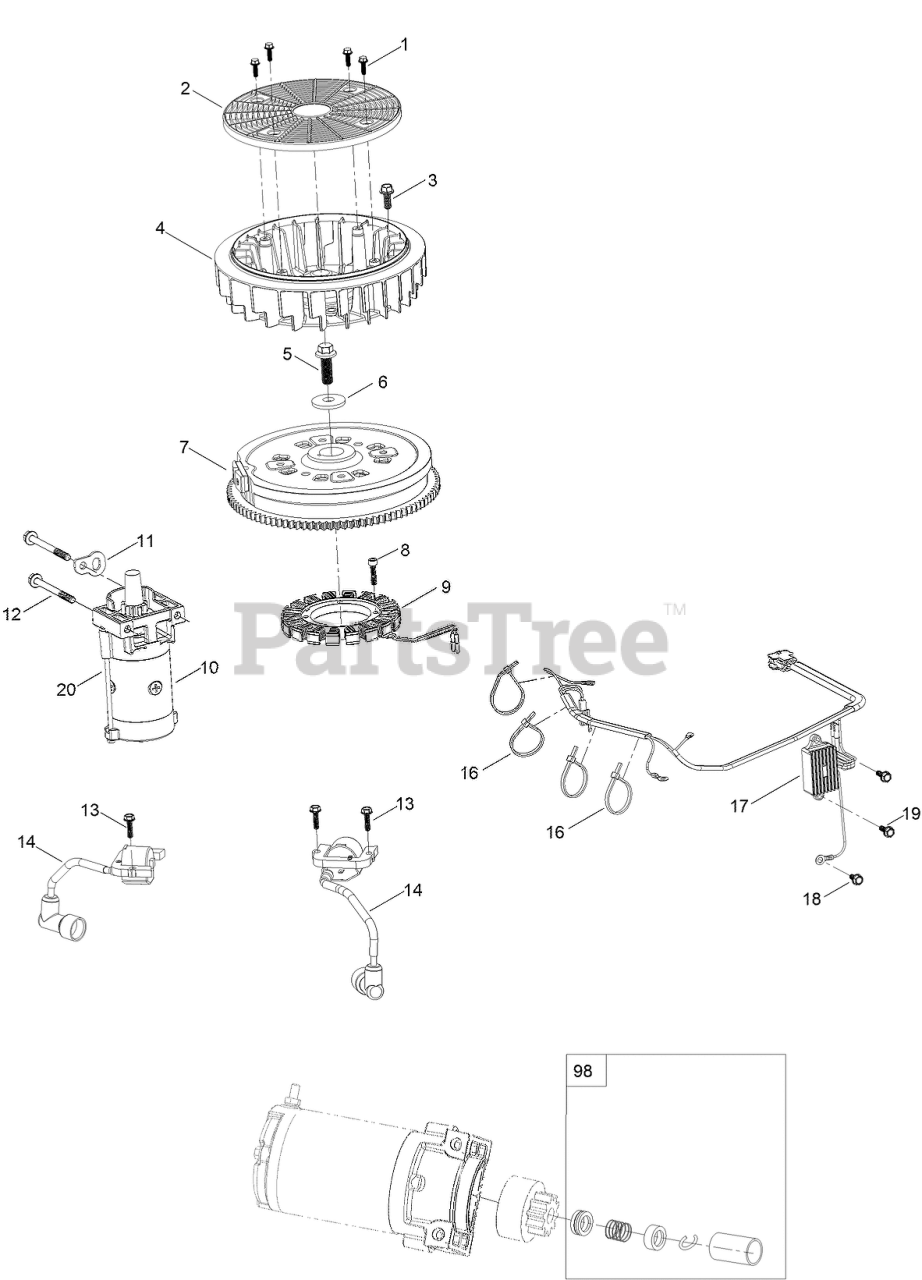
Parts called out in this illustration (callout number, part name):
1	SCREW-HWH
2	SCREEN-ROTATING
3	SCREW-HWH
4	FAN-COOLING
5	SCREW-HWH
6	WASHER-FLAT
7	FLYWHEEL
8	SCREW-HSH
9	ALTERNATOR
10	MOTOR-STARTER
11	BRACKET-LIFT
12	SCREW-HHF
13	BOLT-FLANGE
14	IGNITION COIL ASM
16	TIE-ZIP
17	REGULATOR-VOLTAGE, W/HARNESS
18	SCREW-HHF
19	SCREW-HHF
20	PINION-STARTER
98	STARTER REPAIR KIT
